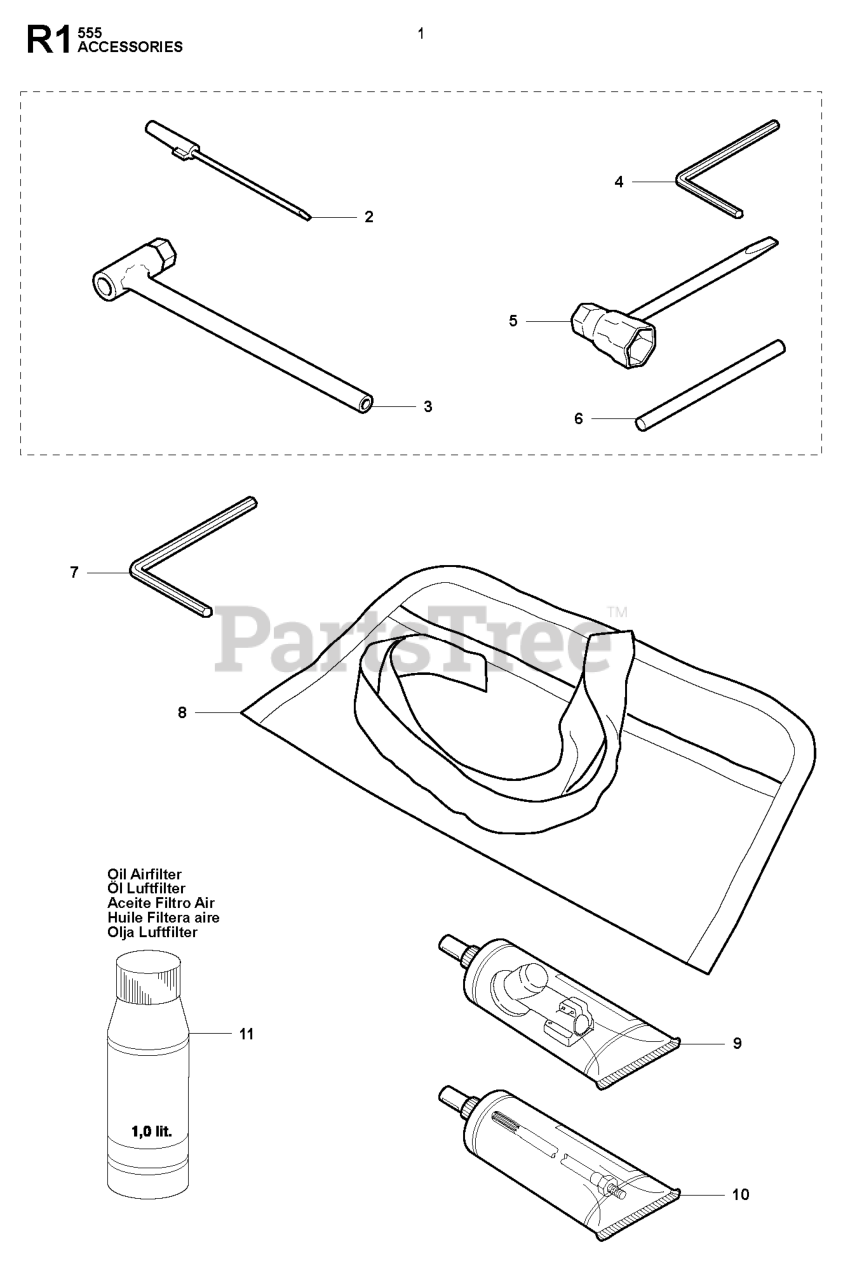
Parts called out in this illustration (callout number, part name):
1	RP ACCESSORY BAG
2	SCREWDRIVER
4	L-KEY WRENCH
5	COMBI TOOL
6	LOCKING PIN
7	KEY
9	BEVEL GEAR GREASE
10	DRIVE SHAFT GREASE (200 G)
11	Air Filter Oil 1l.
